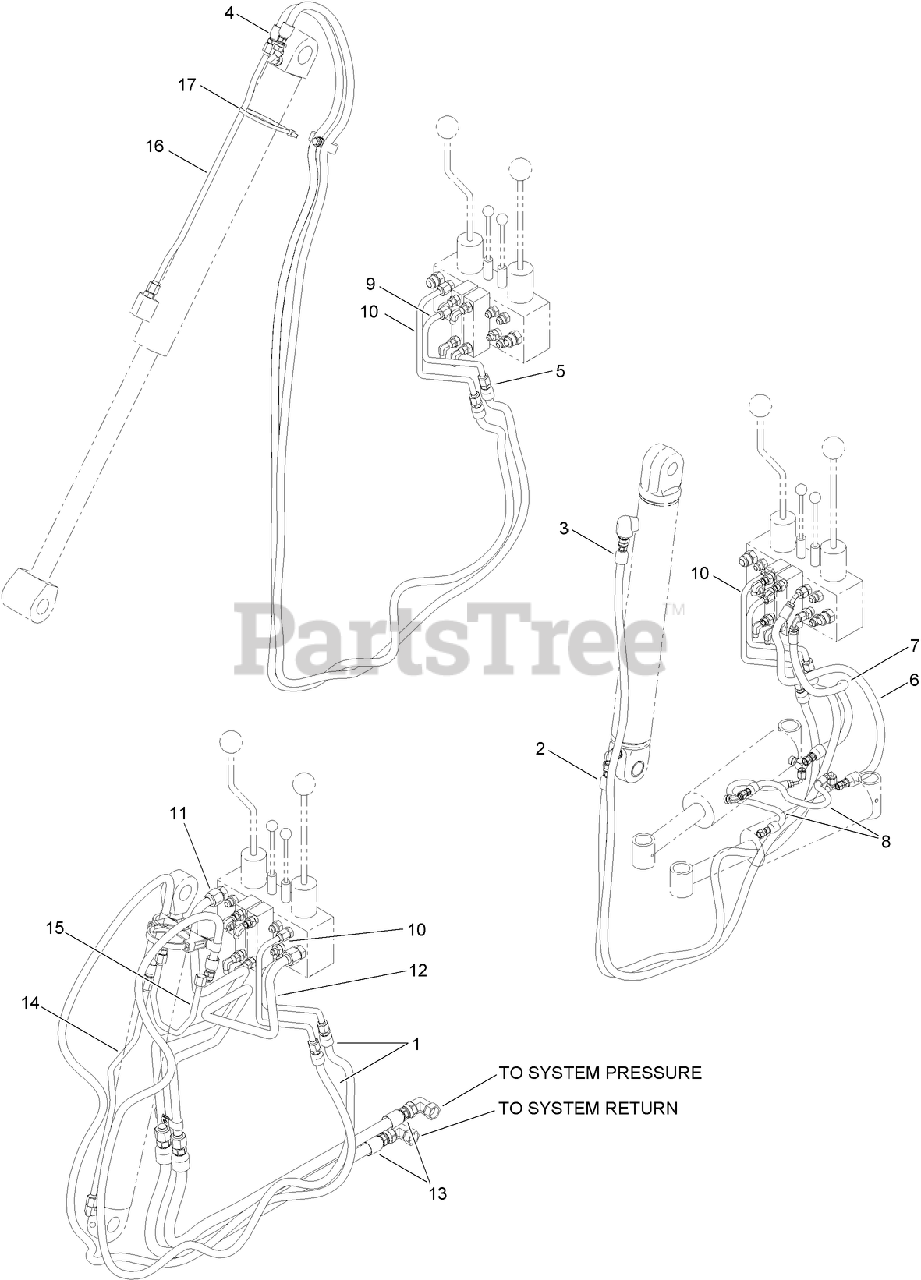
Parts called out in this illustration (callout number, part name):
1	HOSE ASM
2	HOSE ASM
3	HOSE ASM
4	HOSE ASM
5	HOSE ASM
6	HOSE ASM
7	HOSE ASM
8	HOSE ASM-HYD
9	TUBE ASM, VALVE BOTTOM
10	TUBE ASM, VALVE TOP
11	TUBE ASM, BACKHOE RETURN
12	TUBE ASM, BACKHOE SUPPLY
13	HOSE ASM
14	TUBE ASM, CYLINDER
15	TUBE ASM, CYLINDER
16	TUBE ASM, BUCKET
17	TIE-CABLE
